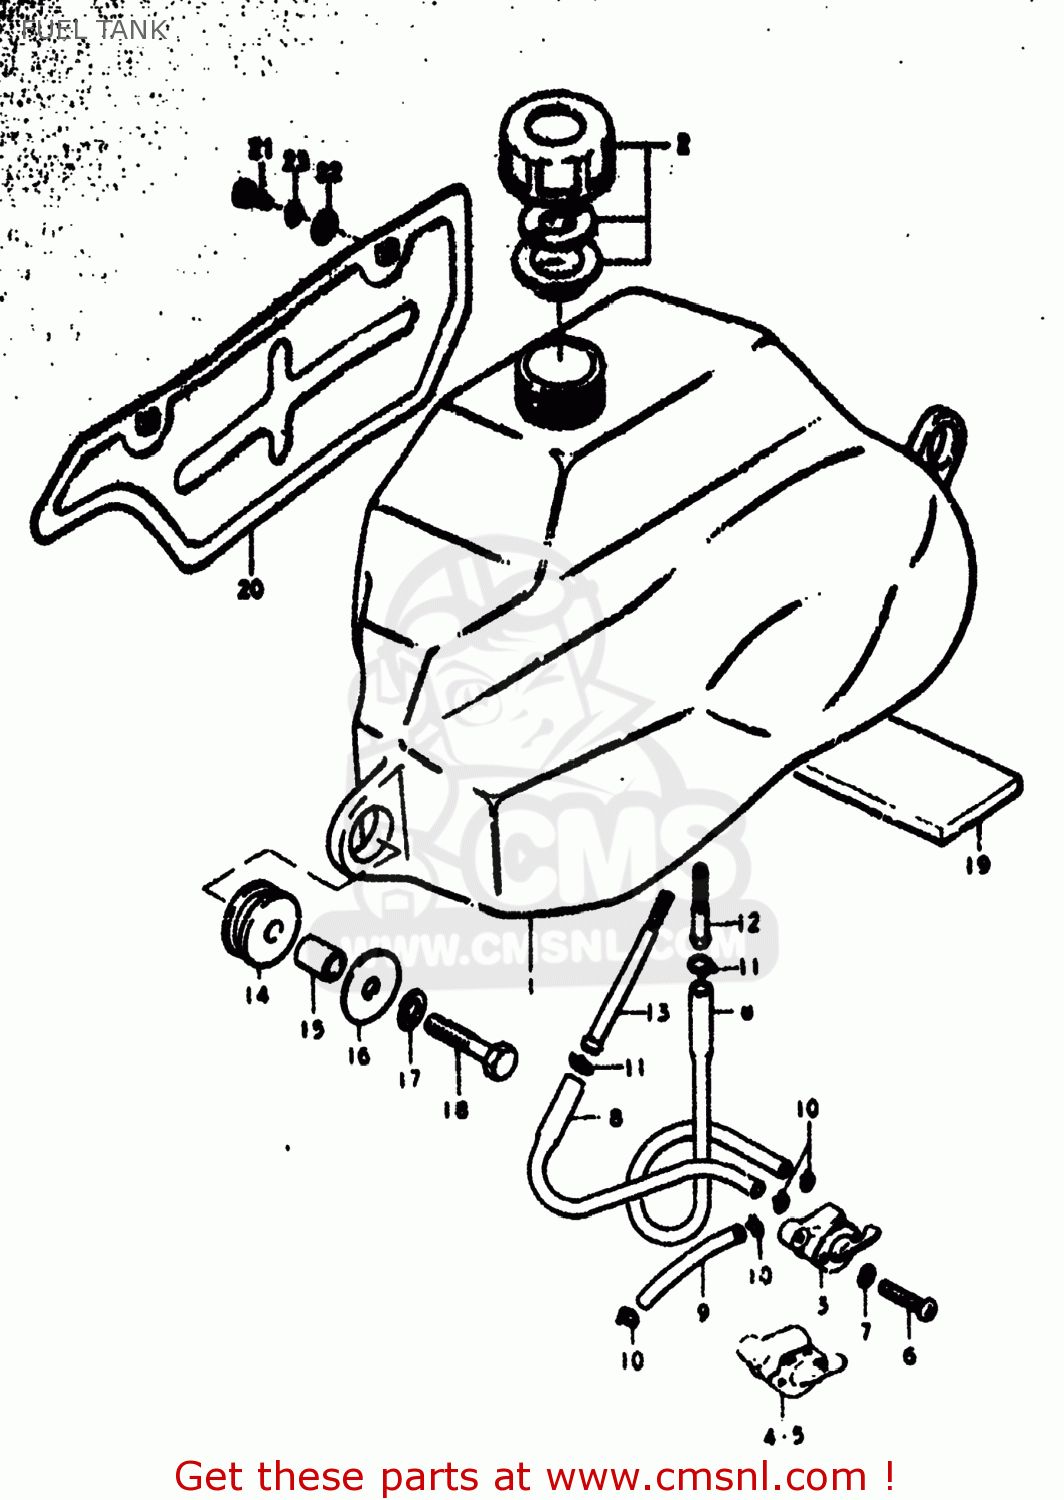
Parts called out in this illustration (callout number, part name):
1	TANK ASSEMBLY,FUEL
2	TANK ASSEMBLY,FUEL
3	COCK ASSY,FUEL
4	COCK ASSEMBLY,FUEL
5	COCK ASSEMBLY,FUEL
6	SCREW
7	LOCK WASHER
8	HOSE,FUEL
9	HOSE
10	CLIP
11	CLIP
12	FILTER,FUEL
13	FILTER,FUEL
14	CUSHION
15	SPACER (8.8X12X15.5)
16	WASHER
17	LOCK WASHER
18	BOLT
19	CUSHION,FUEL TANK
20	BRACKET,FUEL TANK
21	BOLT
22	WASHER
23	LOCK WASHER
